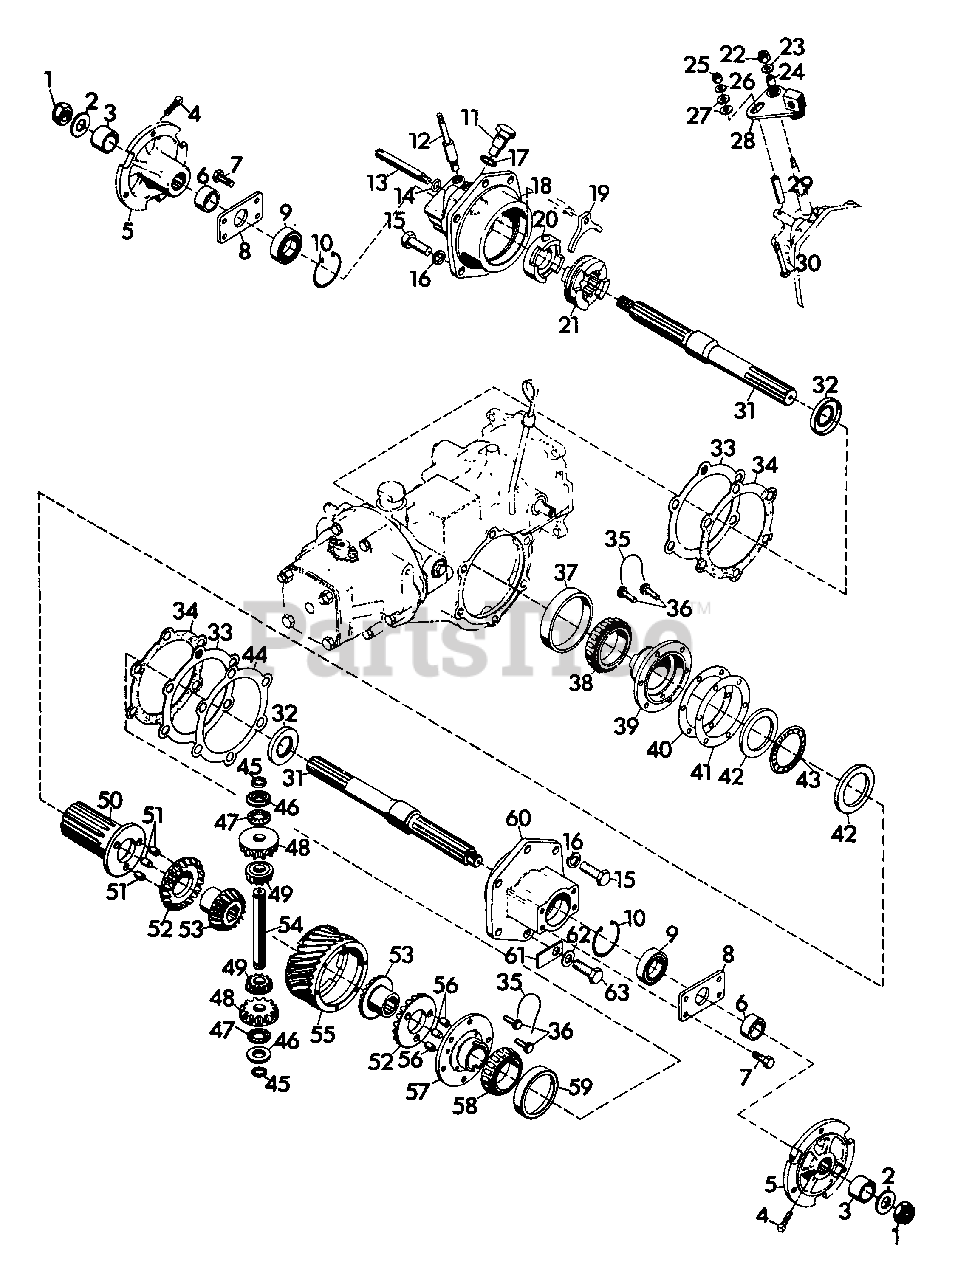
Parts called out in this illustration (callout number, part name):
1	Nut, Hex 3/4-10 Light Thin
2	Washer, Flat .812 x 1.469 x .134
3	Spacer
4	Screw, Set 7/16-14 x 1.00
5	Hub, Wheel
6	Spacer
7	Bolt, Hex 3/8-16 x .750
8	Plate, End
9	Bearing, Ball 1.00 x 2.00 x .562
10	Ring, Retaining 2.00 Bore
11	Bolt, Stationary Clutch
12	Pivot, Stationary
13	Pin, Clutch Sliding
14	O-Ring .438 x .625 x .094
15	Bolt, Hex 1/2-13 x 1.00
16	Washer, Lock 1/2 Reg.
17	Washer, Oil Strainer Nut
18	Housing, Axle 2-Speed
19	Yoke, Shifting
20	Clutch, Stationary
21	Clutch, Shifting
22	Nut, Lock 5/16-18
23	Washer, Flat .344 x .688 x .065
24	Bushing, Nylon .375 x .503 x .875
25	Nut, Lock 1/4-20
26	Washer, Flat .281 x .625 x .065
27	Washer, Flat .406 x .812 x .065
28	Weldment, Arm Shifter
29	Bushing
30	Bolt, 1/4-20 x 2.25 Gr. 8
31	Axle, Straight
32	Seal, Oil 1.188 x 2.00 x .250
33	Shim, Axle Housing .020
34	Gasket, Axle Housing
36	Bolt, Special 5/16-18
37	Cup, Roller Bearing
38	Cone, Roller Bearing
39	Housing, Clutch
40	Shim, Clutch worm Gear .020
41	Shim, Clutch Worm Gear .005
42	Race, Thrust 2.00 x 2.740 x .031
43	Bearing, Needle Thrust .060
44	Shim, Axle Housing .005
45	Ring, Retaining .750 Shaft
46	Spacer, .765 x 1.245 x 2.00
47	Bearing, Needle Thrust .752 x 1.240 x .078
48	Gear, Differential Shifting Bevel
49	Gear, Spider Bevel
50	Shifter, Splined Pinned
51	Pin, Dowel .375 x .375
52	Gear, Pinned Bevel
53	Gear, Differential Bevel
54	Pin, Spider
55	Gear, Worm 8 Start
55	Gear, Worm 6 Start
56	Pin, Dowel .375 x .500
57	Housing, Pinned
58	Cone, Roller Bearing
59	Cup, Roller Bearing
60	Housing, Axle
61	Washer, Oil Drain
62	Washer, Flat .531 x 1.062 x .095
63	Bolt, Hex 1/2-13 x 1.00 Nylon Insert
